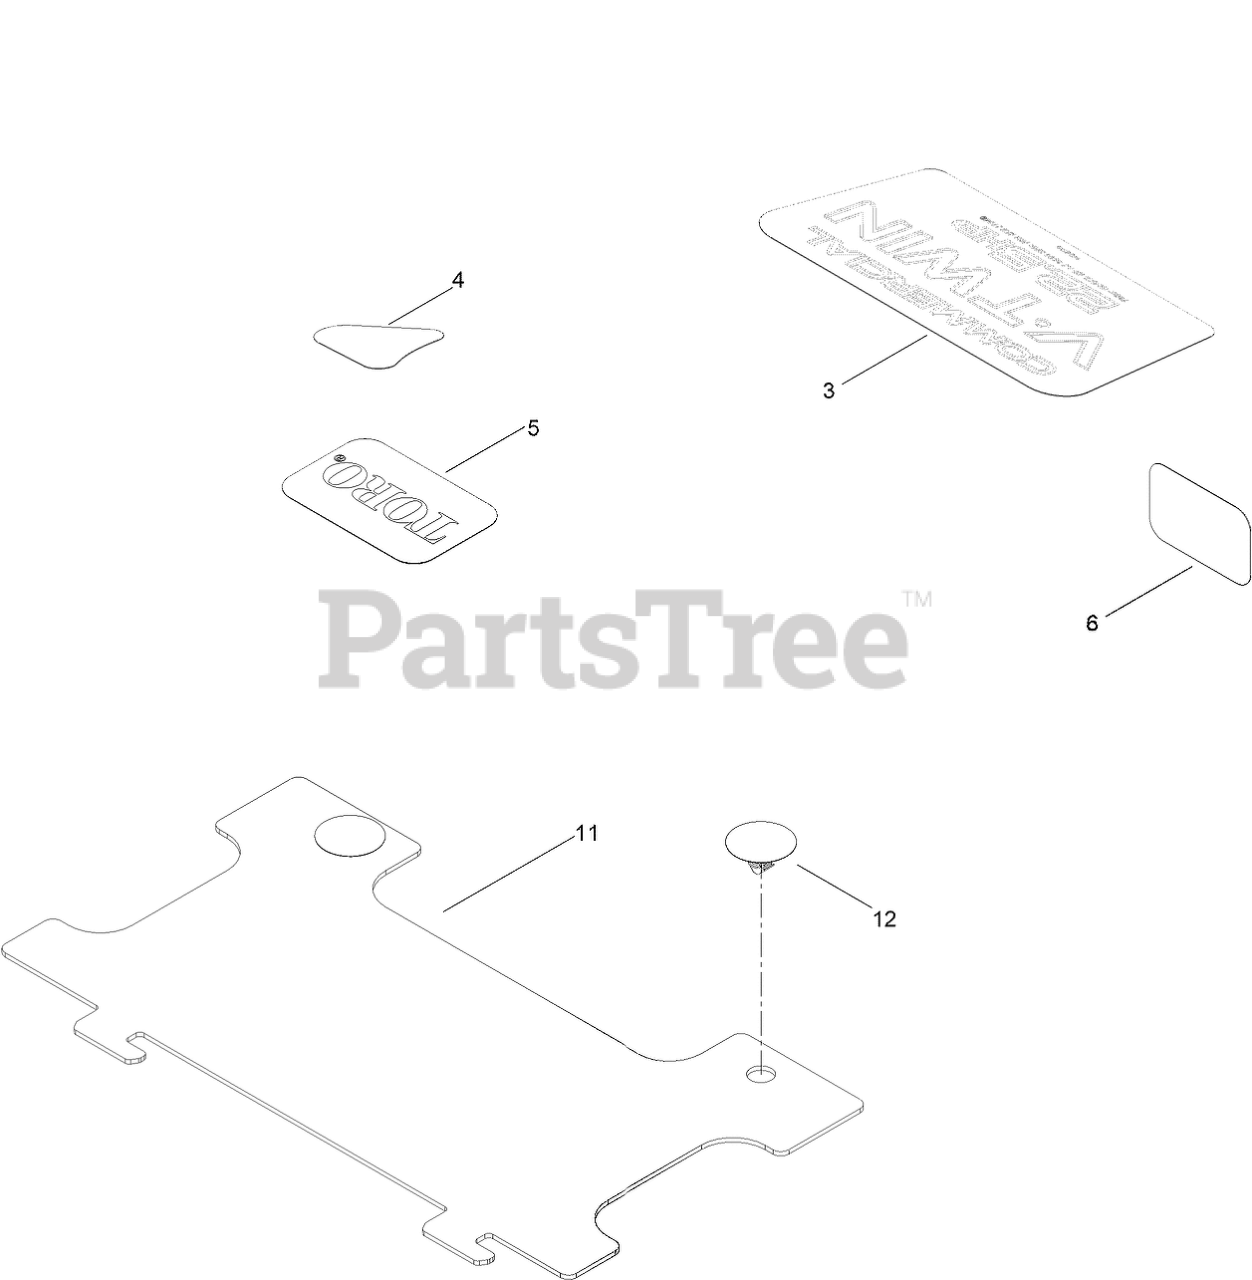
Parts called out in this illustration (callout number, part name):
3	DECAL-ENGINE
4	DECAL-DRAIN, OIL
6	PLACARD-INTAKE
11	SHIELD
12	RIVET-PLASTIC
